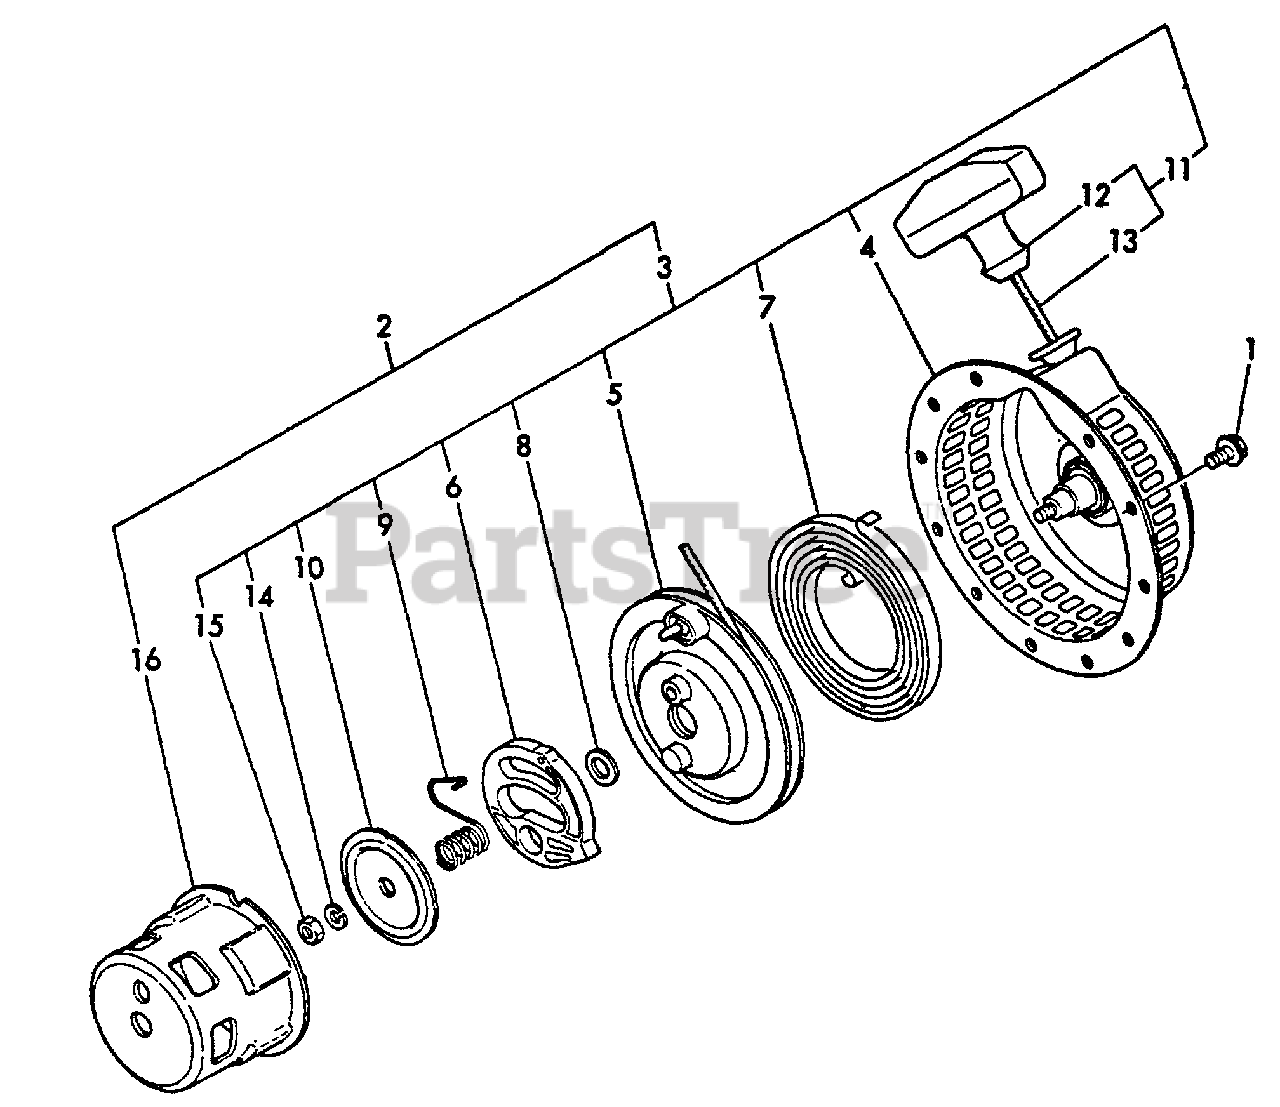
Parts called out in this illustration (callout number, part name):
1	BOLT - 6×12 -- PLATED
2	STARTER ASSY, RECOIL
3	STARTER ASSY, RECOIL
4	CASE, STARTER
5	REEL
7	SPRING, SPIRAL
8	WASHER
9	SPRING
10	PLATE, FRICTION
11	STARTER ROPE ASSY
12	GRIP, STARTER
13	ROPE, STARTER
14	LOCKWASHER - 6
15	NUT - 6
16	PULLEY, STARTER
